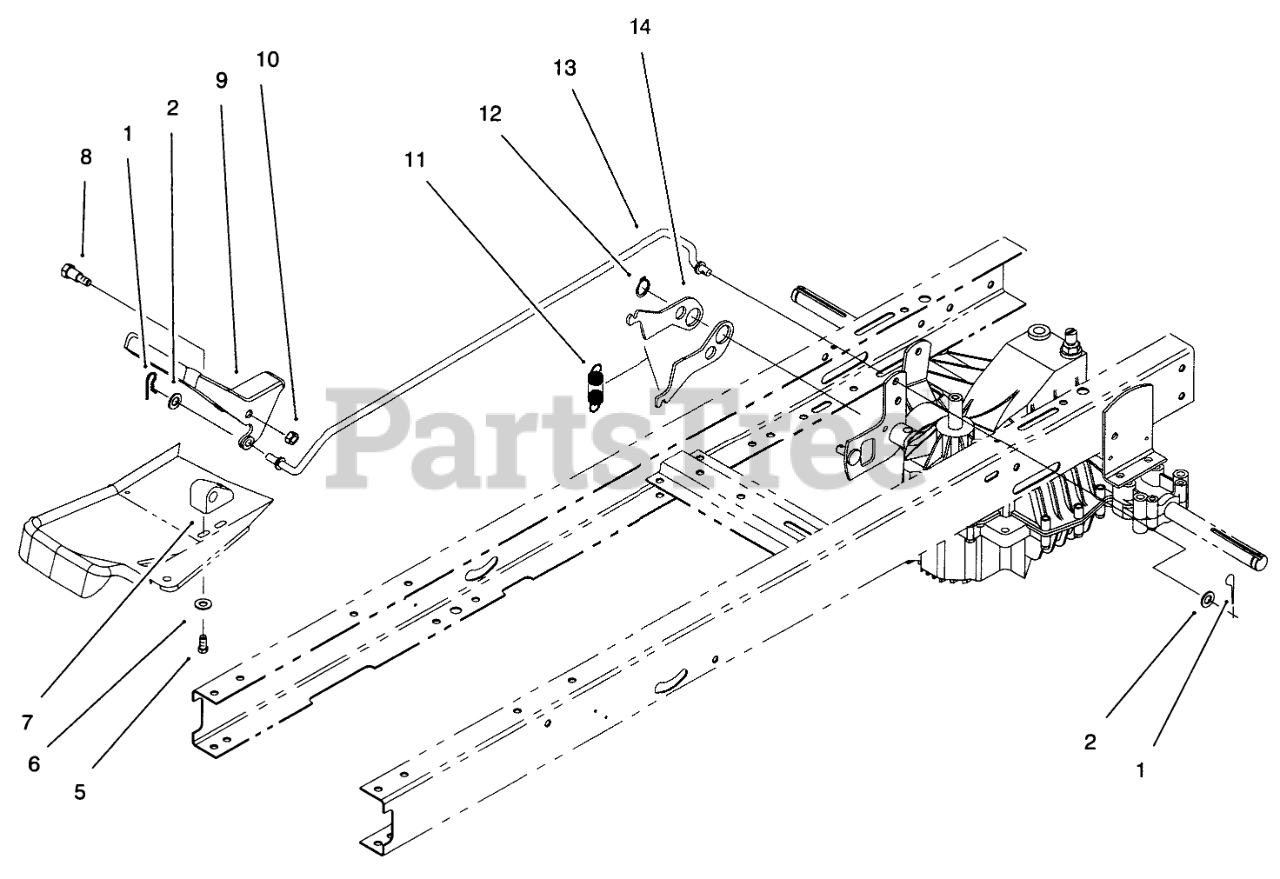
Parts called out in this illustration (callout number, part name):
1	PIN-COTTER
2	WASHER-PLAIN
5	SCREW-PLASTITE
6	WASHER-FLAT
7	BLOCK-PIVOT
8	SCREW-SHOULDER, HH
9	PEDAL SPEED CONTROL
10	NUT-LOCK, NI
11	SPRING-EXTENSION
12	RING-SNAP
13	SPEED CONTROL ROD
14	NEUTRAL RETURN LEVER
